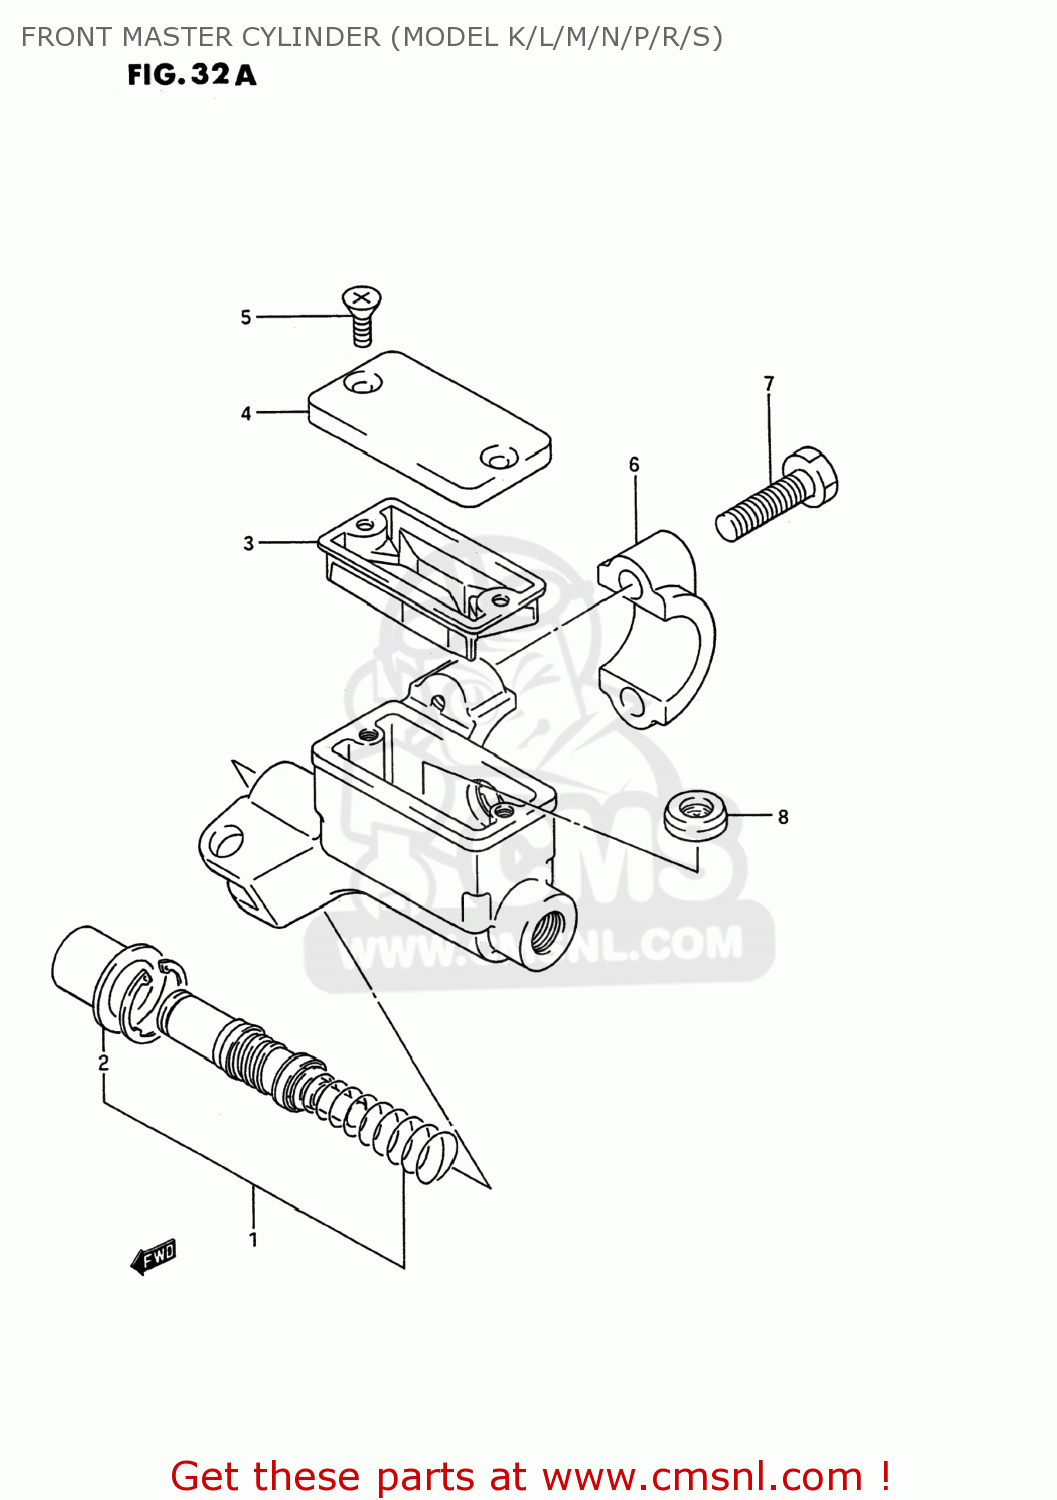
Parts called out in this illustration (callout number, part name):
1	PISTON & CUP SET
2	BOOT
3	DIAPHRAGM
4	CAP
5	SCREW
6	HOLDER
7	BOLT
8	SEPARATOR
